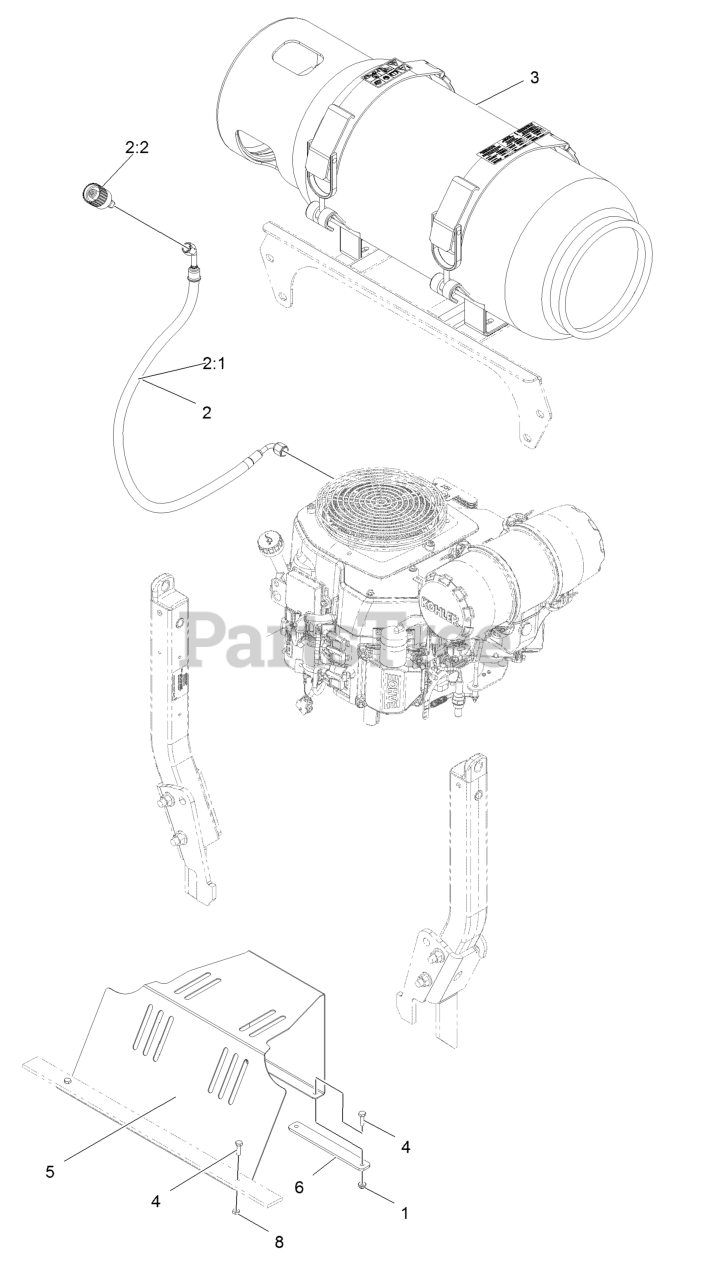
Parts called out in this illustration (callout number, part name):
1	Nut-Nyloc 1/4-20 Flg
2	LPG Hose ASM
2:1	Hose ASM, LPG
2:2	Connector-LP, Straight
3	Tank-LPG
4	Screw-HH 1/4-20 X 7/8
5	Sheild-Fan
8	Nut-Jam 1/4-20
